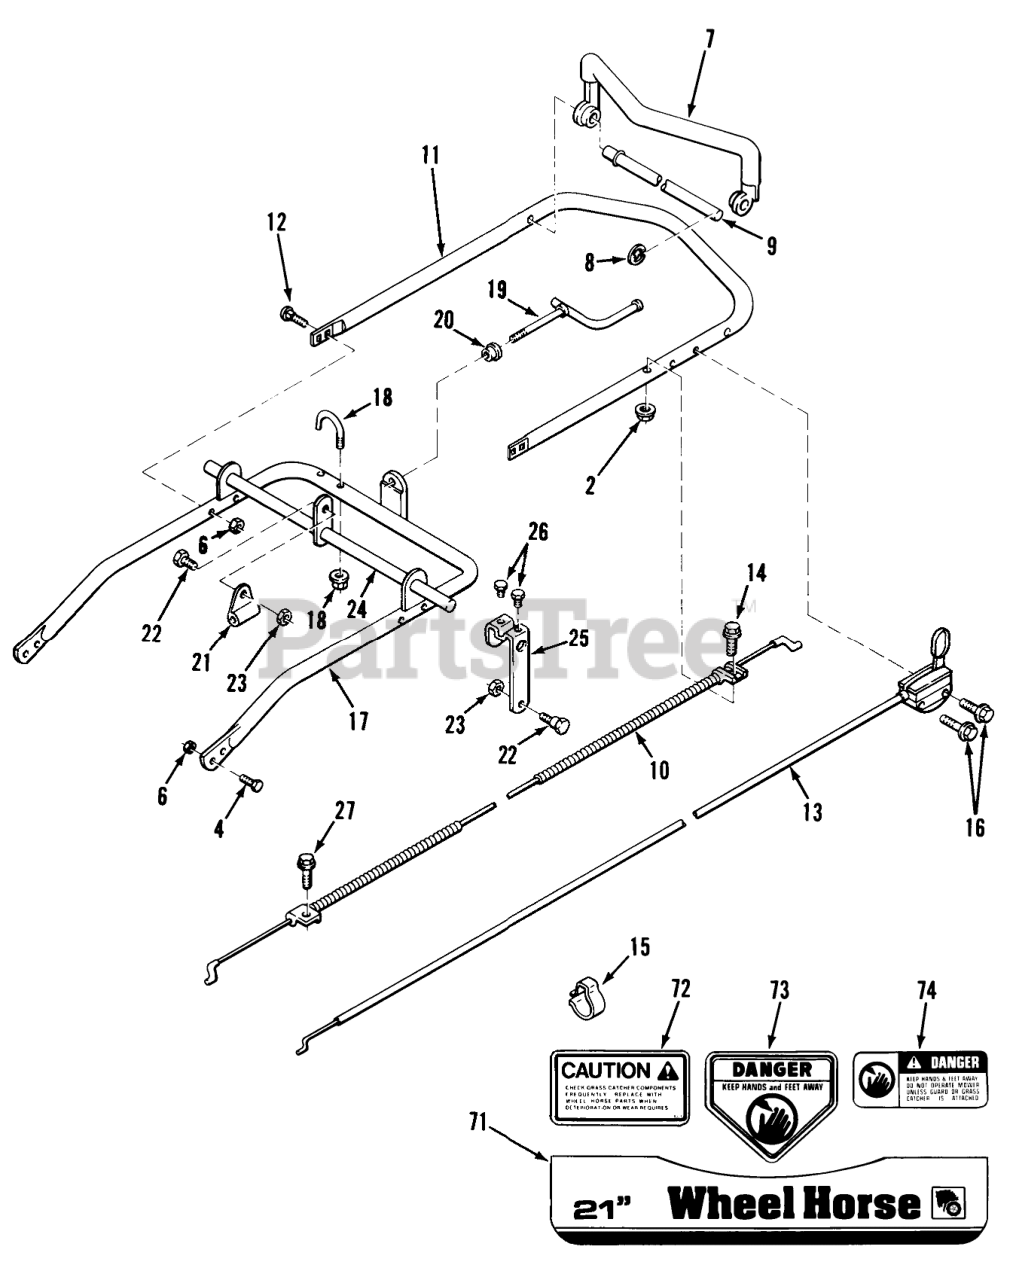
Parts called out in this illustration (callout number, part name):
2	Hex Nut 1/4-28
4	SCREW 5/16- 18X3/4
6	Flanged Nut
7	Deadman Blade Control Lever
8	GRIP RING
9	Deadman Control Axle
10	Blade Control Cable
11	Upper Handle
12	Bolt-Carriage
13	ASSY-THROTTLE CONT
14	Hex Bolt 1/4-28 x 1 1/2
15	Cable Housing Clamp
16	SELF TAPPING SCREW
17	LOWER HANDLE
18	Recoil Starter Stop w/ Nut
19	Height Adjustment Crank
20	Crank Thrust Bearing
21	Threaded Crank Holder
22	SHOULDER BOLT
23	Hex Nut 7/16-14
24	Height Adjustment Top Rod
25	Height Adjustment Top Arm
26	Set Screw 3/8-16
27	BLADE SCREW
71	Decal-Wheel Horse 21"
72	DECAL-CAUTION
73	Decal-Danger
74	Danger Decal
